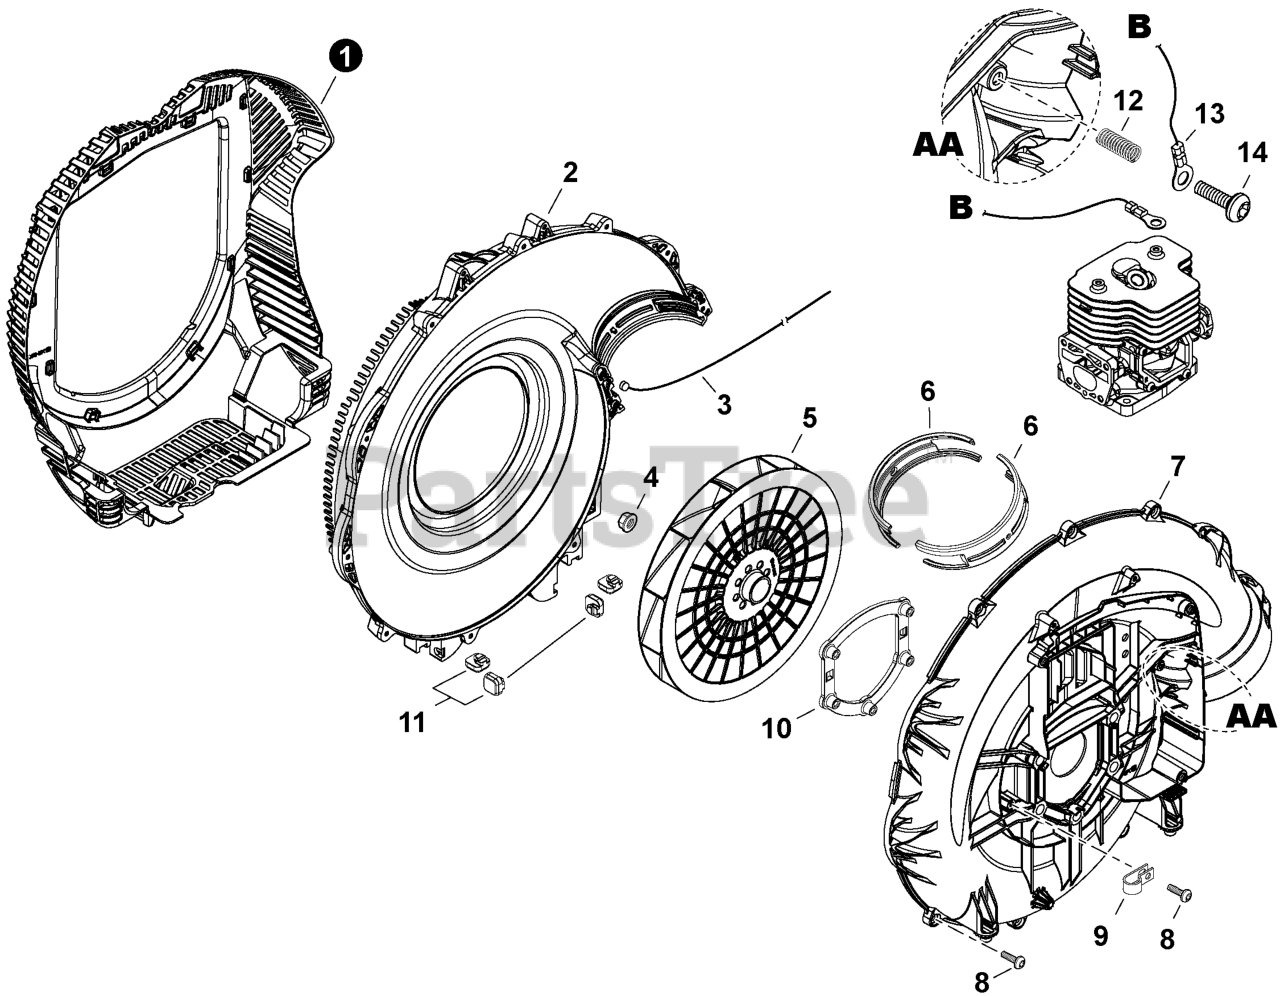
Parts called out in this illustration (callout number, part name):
1	GUARD, DEBRIS
2	COVER, FAN
3	WIRE, ANTI-STATIC
4	NUT, FLANGE 10x1.25
5	FAN, BLOWER
7	CASE, FAN
8	BOLT, TORX 5x20
9	CLIP
10	PLATE, ENGINE
11	CUSHION
12	SPRING, COMPRESSION
14	BOLT, TORX 5x12
